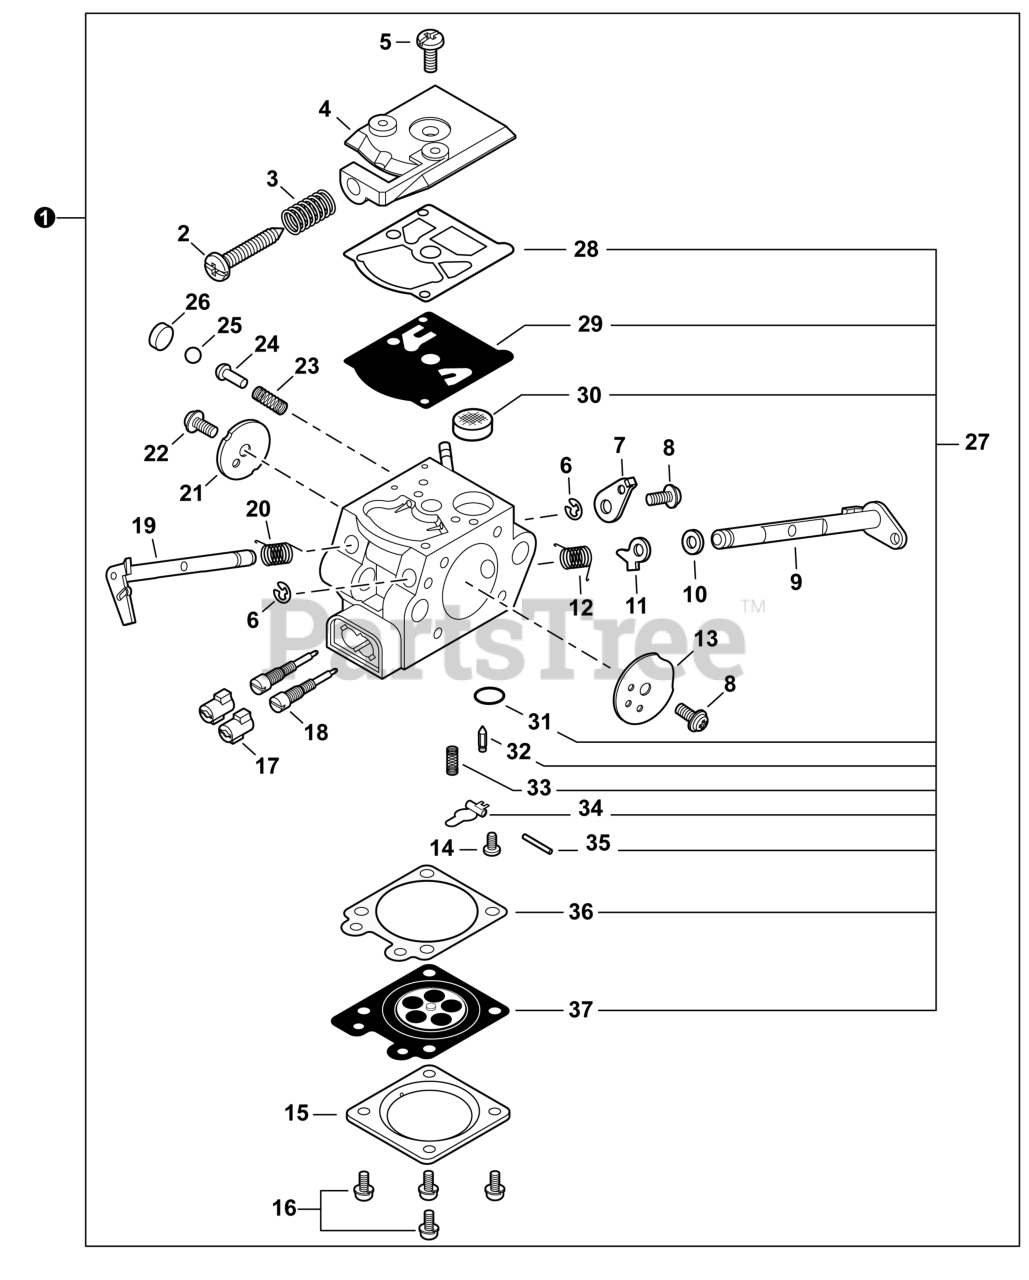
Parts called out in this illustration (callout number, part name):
1	CARBURETOR WT-1049
2	SCREW, IDLE ADJUST
3	SPRING, IDLE ADJUST
4	COVER, FUEL PUMP
7	LEVER, THROTTLE
9	SHAFT, CHOKE
11	LEVER, FAST IDLE
13	VALVE, CHOKE
14	SCREW, METERING LEVER PIN
15	COVER, METERING DIAPHRAGM
17	CAP, LIMITER
18	NEEDLE, MIXTURE
19	SHAFT, THROTTLE
20	SPRING, THROTTLE RETURN
21	VALVE, THROTTLE
23	SPRING, START VALVE
24	PISTON ASSY
27	REPAIR KIT, CARBURETOR
28	GASKET, FUEL PUMP
29	DIAPHRAGM, PUMP
30	SCREEN, FUEL INLET
31	PLUG, WELCH
32	VALVE, INLET NEEDLE
33	SPRING, METERING LEVER
34	LEVER, METERING
35	PIN, METERING LEVER
36	GASKET, METERING DIAPHRAGM
37	DIAPHRAGM, METERING
